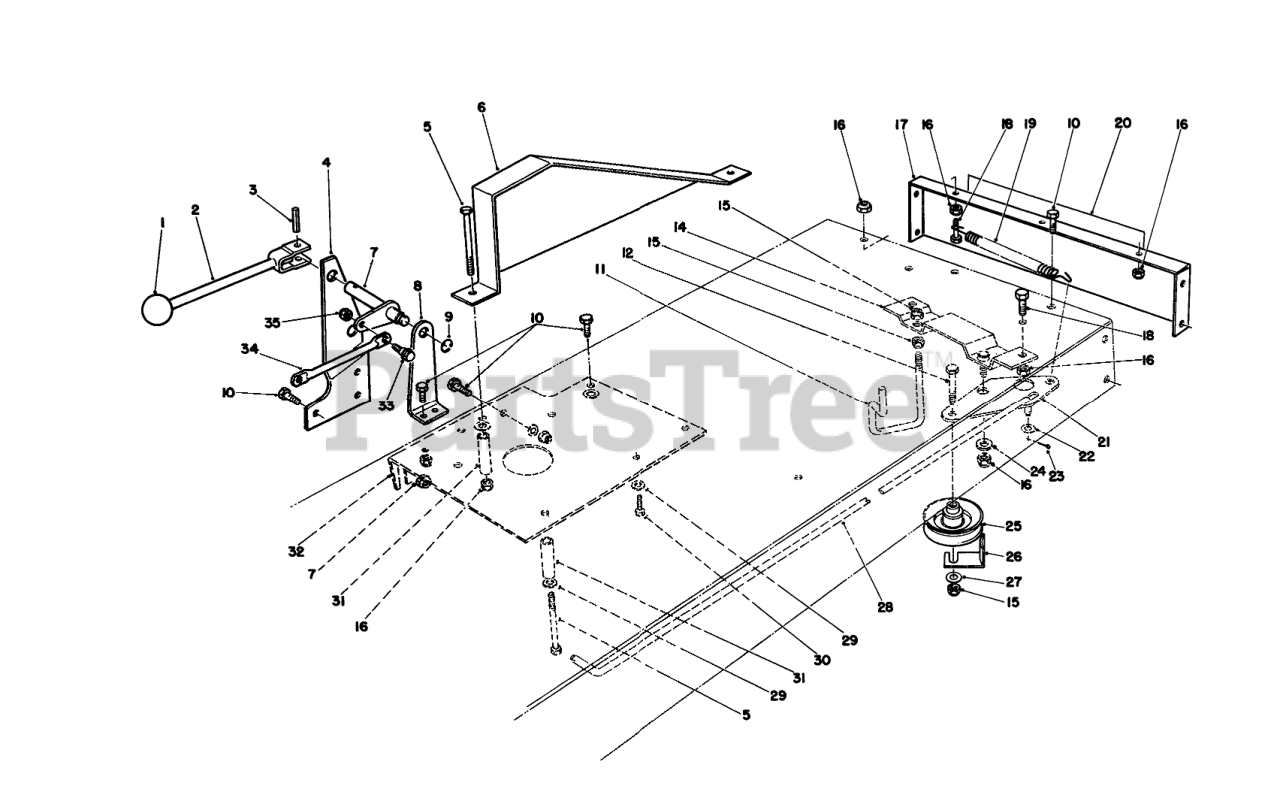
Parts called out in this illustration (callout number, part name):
2	Lever W.A.-Engage
3	PIN-ROLL
4	Pivot-Outer
5	SCREW-HH
6	CHAIN GUARD R
7	PIVOT SHAFT WA
8	Bracket-Pivot, Inner
9	RING-RETAINING, EXTERNAL
10	SCREW-HH
11	BELT GUIDE
12	SCREW-HH
14	TRACT SUPT BRKT WA B
15	NUT-LOCK, NI
16	NUT-LOCK, NI
17	REAR FRAME R
18	SCREW-HH
19	TRACTION SPRING
20	DECAL - REAR FRAME
21	TRACT PIVOT BRKT B
22	WASHER-FLAT
23	PIN-COTTER
24	WASHER-FLAT
25	PULLEY-IDLER
26	RETAINER-BELT
27	WASHER-FLAT
28	TRACTION ROD
29	WASHER-PLAIN
30	Screw-Mach. Hex. Hd.
31	OUTER TUBE SPACER
32	REINF PLATE R
33	SCREW-SHOULDER
34	LINK-BELLCRANK
35	NUT-HEX
